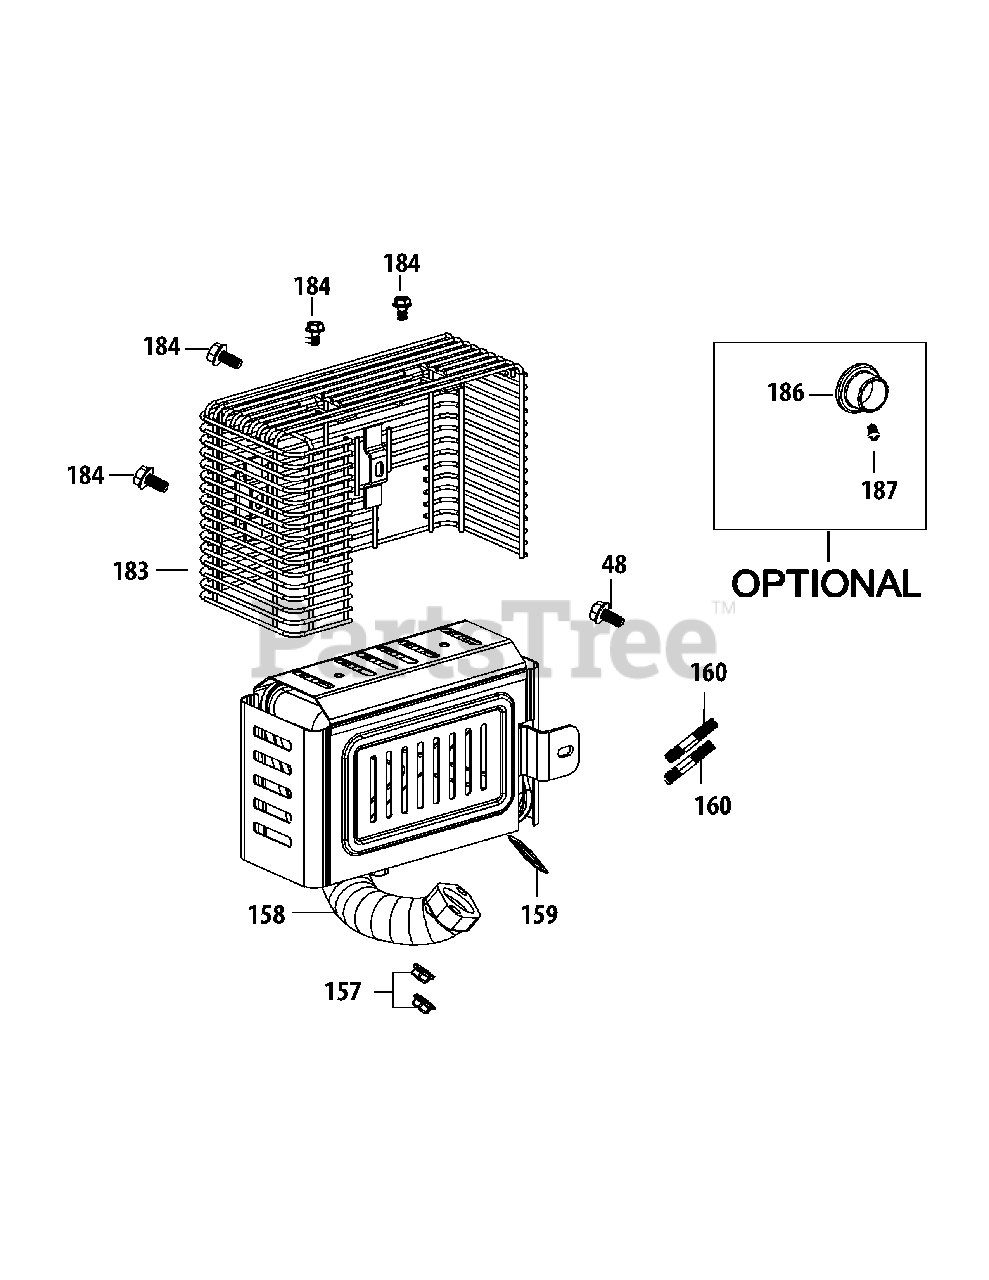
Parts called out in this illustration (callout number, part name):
48	Bolt M6×14
157	Nut M8
158	Muffler Assembly
159	Exhaust Pipe Gasket
160	Muff Stud M8×47
160	Muffler Stud Assembly
183	Wire Mesh Shield
184	Bolt M6×12
186	Spark Arrestor
187	Spark Arrestor Screw
